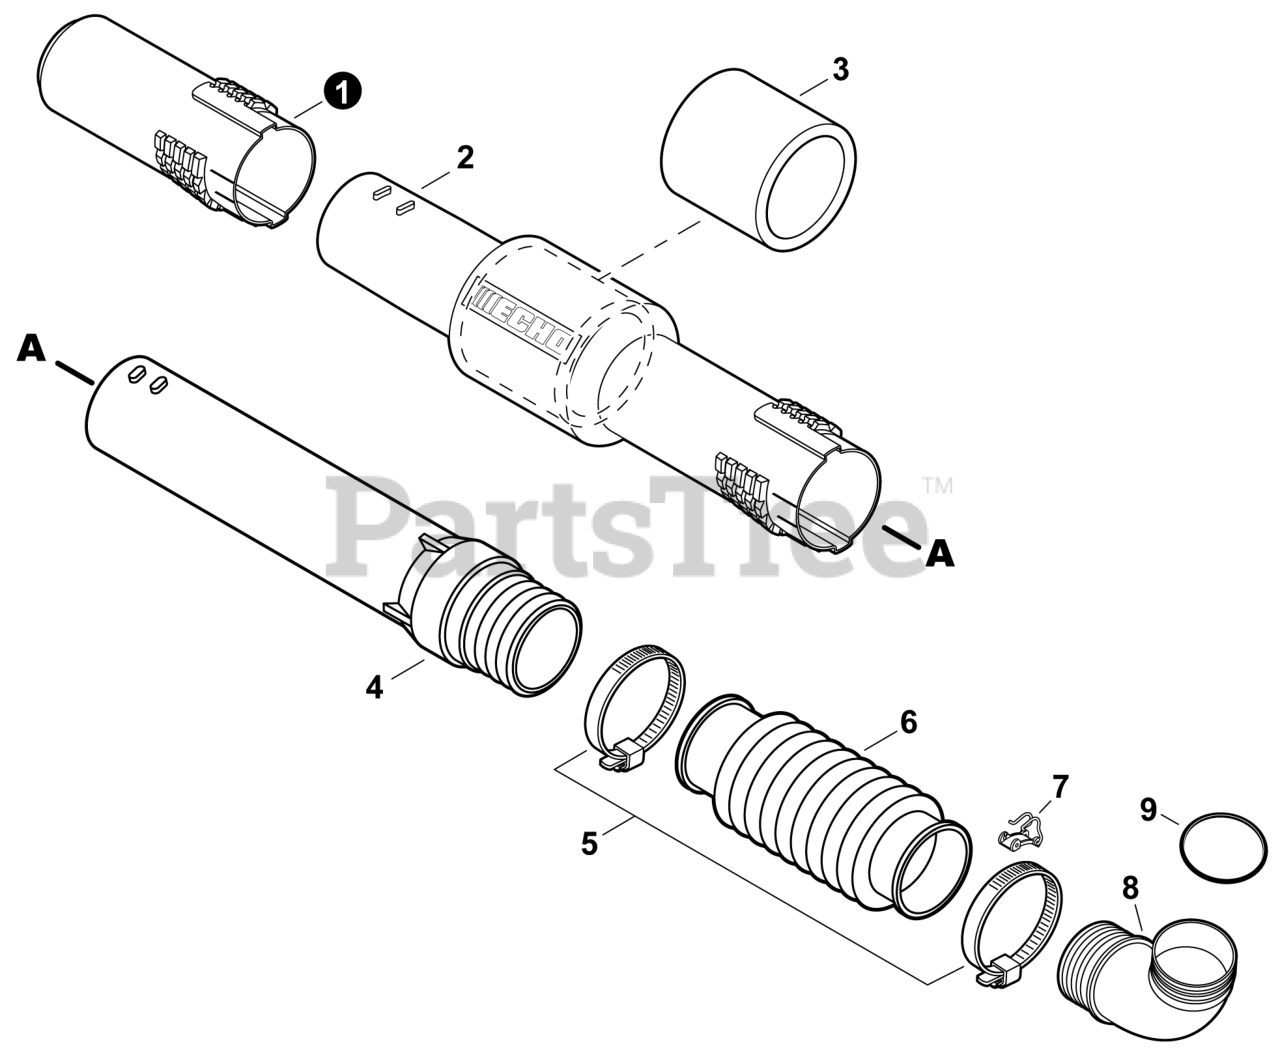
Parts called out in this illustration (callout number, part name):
1	TUBE, BLOWER - NOZZLE
2	TUBE, BLOWER - STRAIGHT
3	PAD, FOAM
4	TUBE, BLOWER - SWIVEL
5	CLAMP - BAND 77.8 MM / 101.6 MM
6	TUBE, BLOWER - FLEXIBLE
7	CLIP, CABLE
8	TUBE, BLOWER - ELBOW
